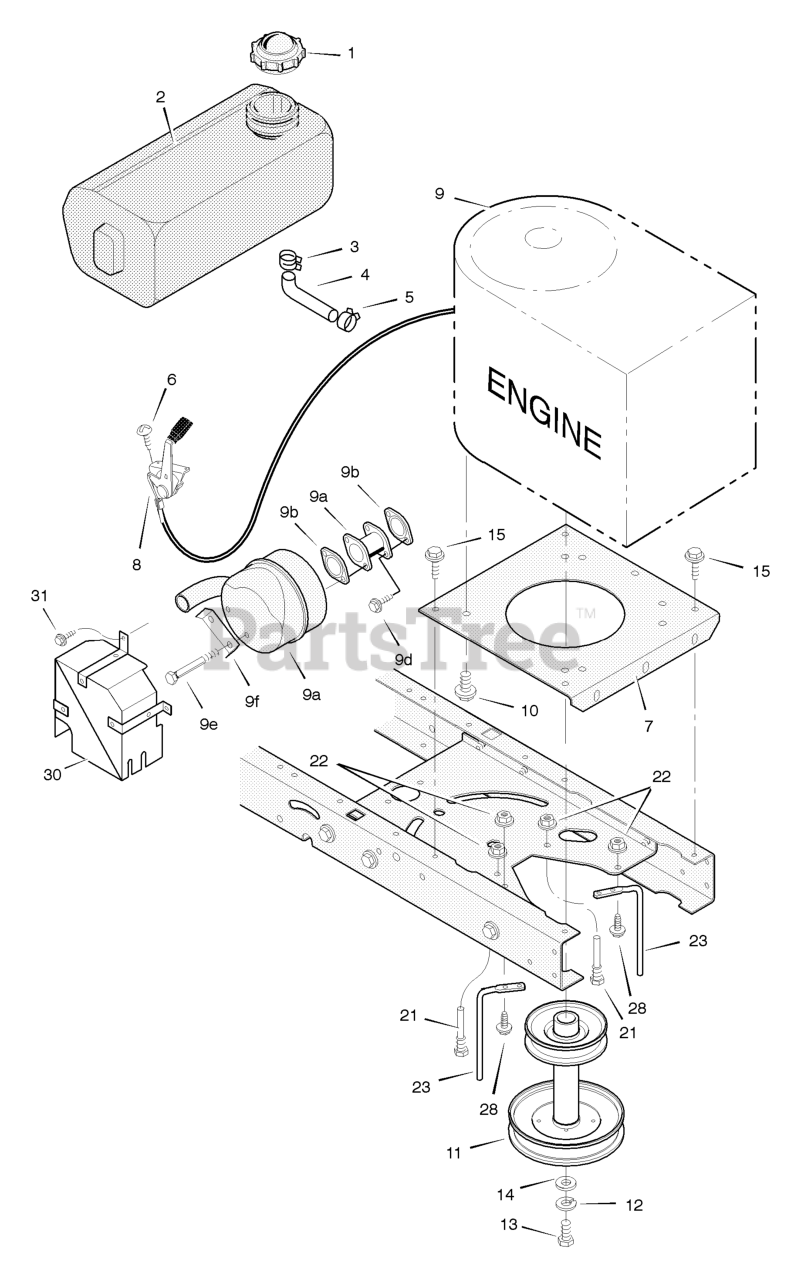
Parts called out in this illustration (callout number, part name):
1	Fuel Cap
2	Fuel Tank
3	Hose Clamp
4	Fuel Line (Must cut to length)
5	Hose Clamp
7	Plate, Engine
8	Throttle Control
9	Engine, Briggs & Stratton *
9A	Muffler
9B	GASKET, Exhaust
9C	Adapter, Muffler
9D	Screw, Adapter
9E	Bolt, Muffler
9F	Lock, Screw
10	Bolt, Engine Mount
11	STACK PULLEY ASSEMBLY
12	Lockwasher
13	Bolt, Hex
21	Guide, Belt
22	Nut, Flange
23	Guide, Belt
28	Screw
30	Shield, Heat
